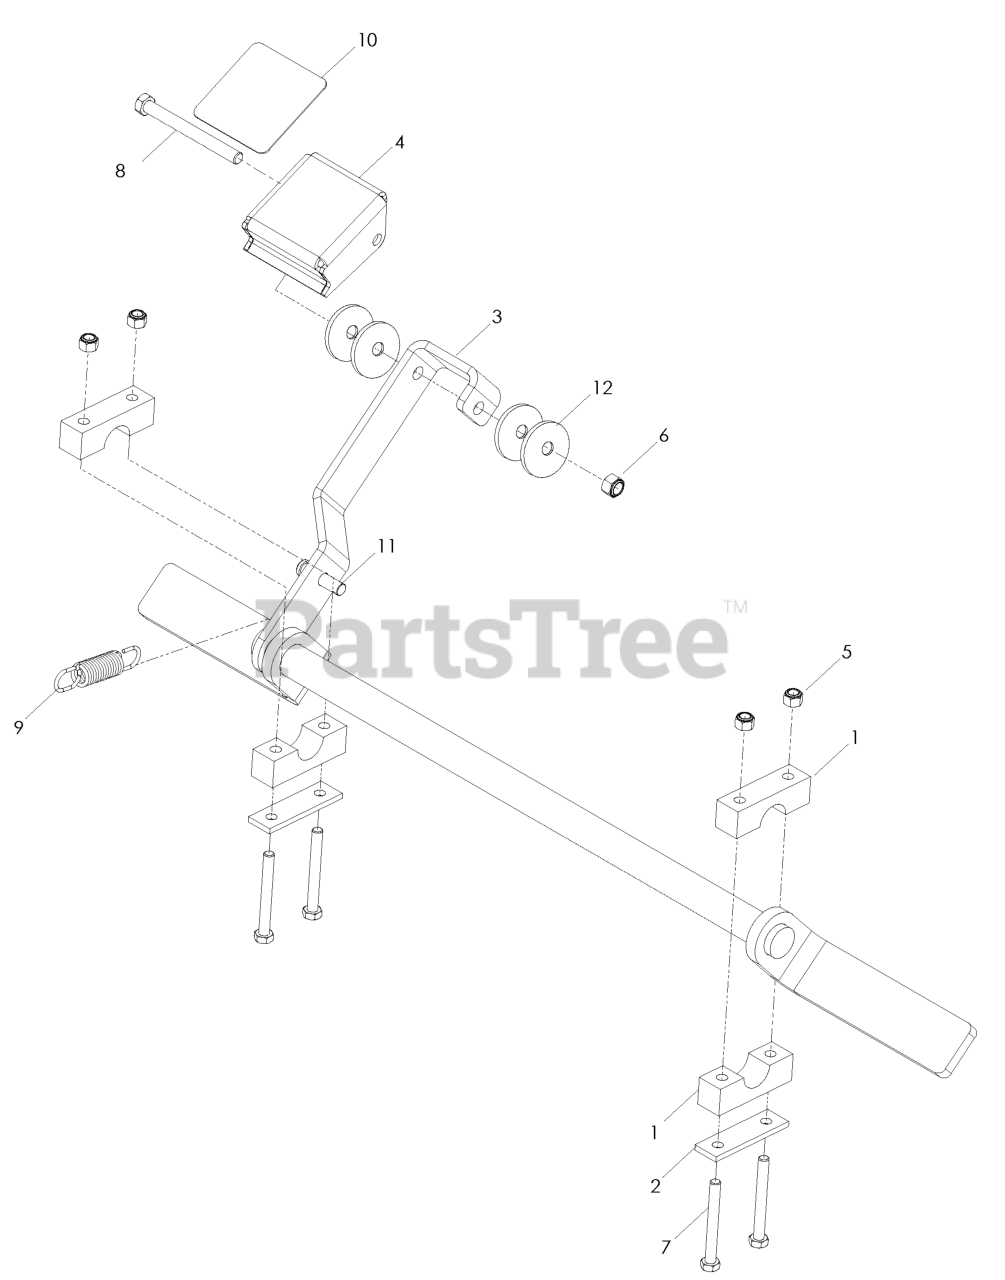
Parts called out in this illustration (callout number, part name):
1	PILLOW BLOCK
2	REINFORCEMENT BAR
3	PARK BRAKE
4	PEDAL, BLACK
5	NUT 5/16 NYLOC
6	NUT 3/8-16 NYLOC
7	HCS 5/16C X 2-3/4
8	HCS3/8-16.X
9	SPRING, EXTENSION
10	ANTI-SKID PAD
11	CLEVIS PIN, 3/8 X 1 1/2
12	WASHER, FRICTION
